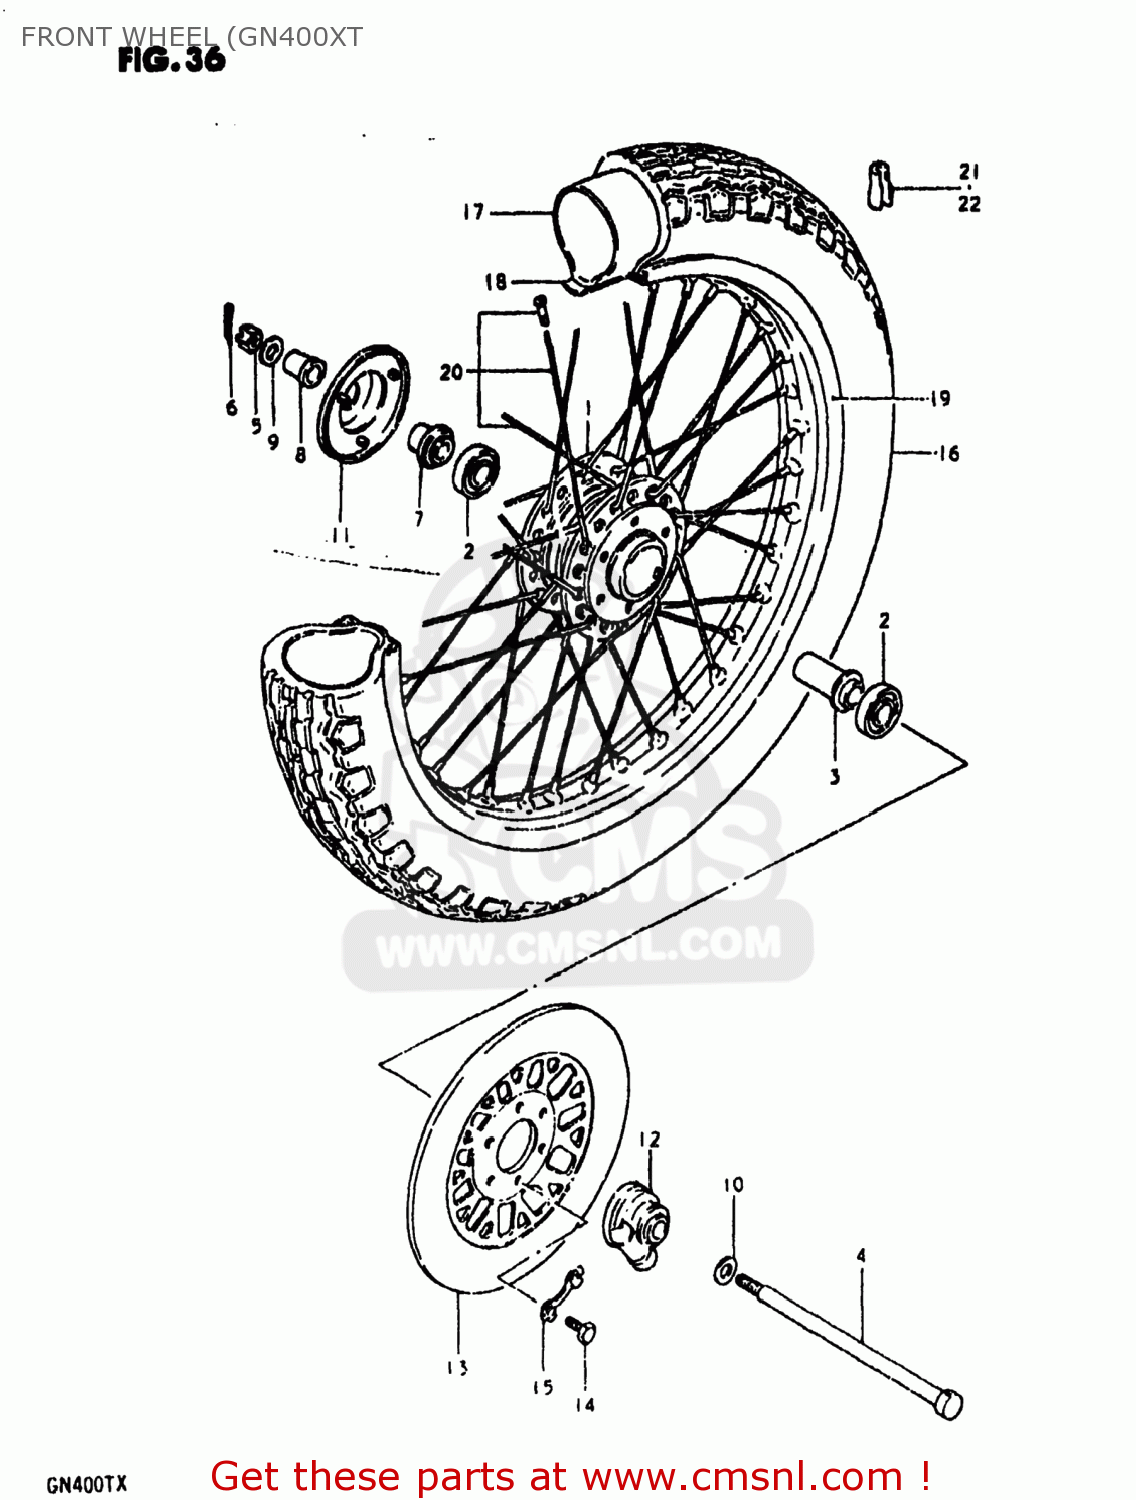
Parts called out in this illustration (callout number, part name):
1	DRUM,FRONT HUB
2	BEARING
3	SPACER,FR HUB BEARING
4	AXLE,FR
5	NUT 12MM
6	COTTER PIN
7	SPACER,FR AXLE,R
8	SPACER
9	WASHER
10	WASHER(15.5X26X2.3)
11	COVER,FR HUB,R
12	BOX ASSEMBLY,SPEEDOMETER GEAR
13	DISC,FR BRAKE
14	BOLT(8X25)
15	WASHER
16	TIRE,FRONT
17	TUBE,INNER
18	PROTECTOR,WHEEL,INNER
19	RIM,FRONT WHEEL (1.85X18)
20	SPOKE SET,FRONT
21	BALANCER,WHEEL (B)
22	BALANCER,WHEEL (30G)
